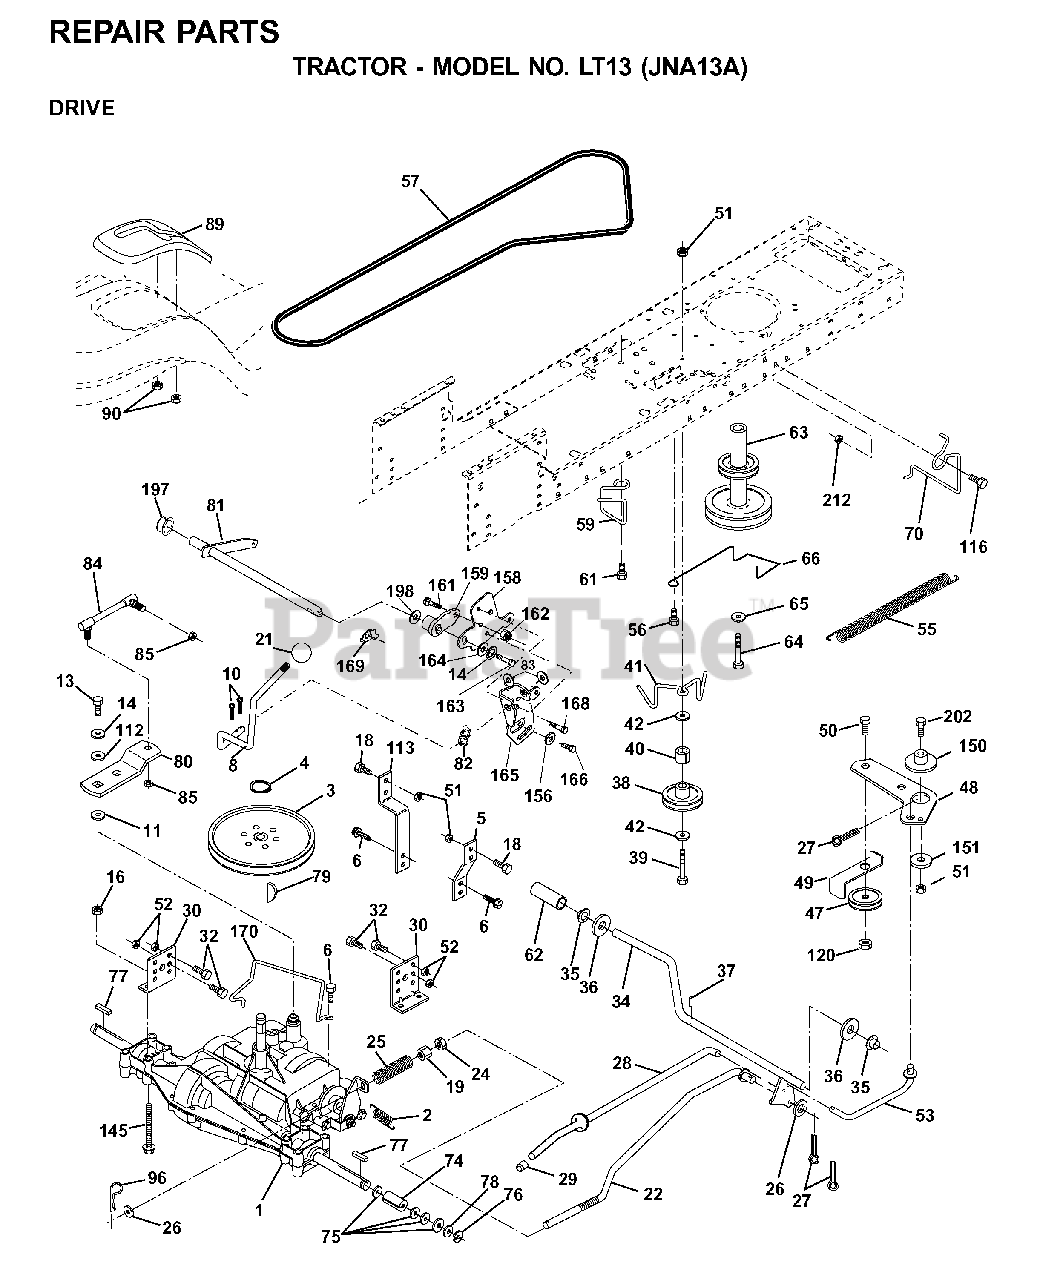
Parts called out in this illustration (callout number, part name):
2	SPRING,BRAKE RETURN
3	PULLEY TRANS
4	RETAINING RING LT
5	STRAP TORQUE
6	SCREW 5/16"
8	ROD SHIFT FENDER ADJUST STLT
10	PIN COTTER
11	WASH-SHFT PLT LT
13	BOLT 1/4-28X3/4
14	LOCKWASHER
16	NUT.71038.31-18.HEX.NYLOCK
19	NUT
21	KNOB.DUCKHEAD.1/2
22	ROD BRAKE
24	NUT
25	SPRING ROD LT
27	COTTER PIN
28	ROD, PARKING BRAKE
29	PLUNGER CAP
30	BRKT, MOUNT TRNSAXLE
32	BOLT
34	SHAFT, FOOT PEDAL
35	BEARING.NYLON
36	WASHER LT
37	DRIVE PIN
38	PULLEY.FLAT
39	BOLT
40	SPACER, SPLIT
41	KEEPER, BELT IDLER
42	WASHER
47	IDLER PULLEY
48	BELLCRANK, CLUTCH
49	RETAIN BELT
50	BOLT
51	LOCKNUT
52	LOCKNUT
53	LINK, CLUTCH LT
55	SPRING, RETURN LT
57	V-BELT
59	KEEPER, BELT CENTER
61	SCREW 3/8-16X3/4
62	PEDAL COVER
63	ENGINE PULLEY
64	BOLT
65	LOCKWASHER
66	KEEPER BELT ENGINE
70	KEEPER BELT ENG
74	SPACER AXLE
76	E-RING LT
77	SQUARE KEY
80	ARM SHIFT
82	SHIFT SPRING
83	WASHER
85	NUT LOCK CENTER 1/4 -28 FNTHD
89	SHIFT CONSOLE
96	RETAINER M
112	WASHER LT
113	STRAP TORQUE LH LT
116	BOLT D
120	NUT LOCK FLG 3/8-16 UNC
150	SPACER, RETAINER
151	WASHER 12/32X2X10GA
156	WASHER.SRRTD.5/16
158	BRACKET
159	HUB
161	BOLT
162	NUT.CROWNLOCK.1/4
165	RP BRACKET
168	BOLT.SHOULDER.5/16-18X
169	PLATE.FASTENING.CROSS.SHAFT
197	NYLINER SNAP 5/8" ID
198	WASHER.NYL.7/8IDX.105"HYD CR
202	BOLT
212	NUT
